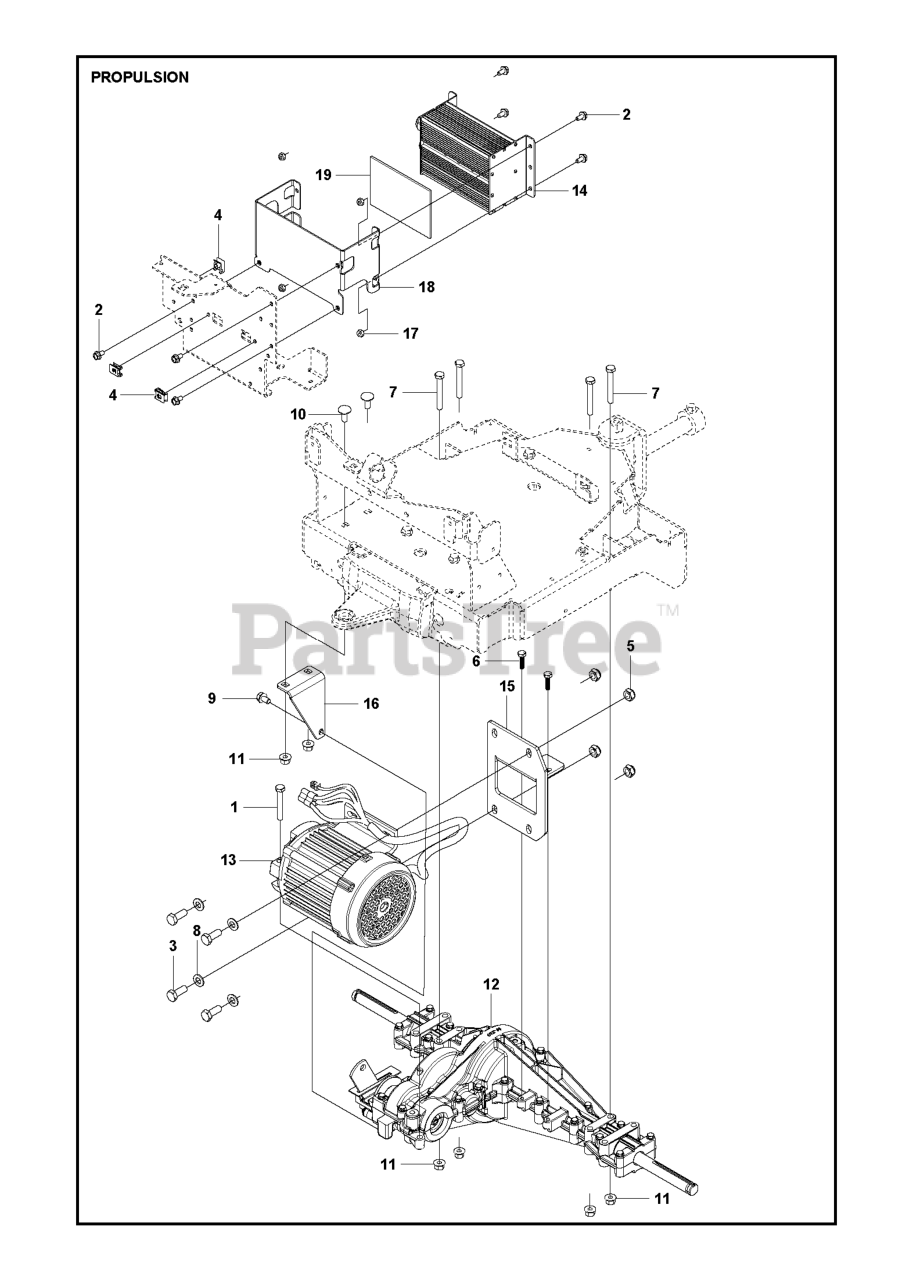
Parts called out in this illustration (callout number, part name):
2	SCREW EHHFM
3	Screw M10x25
6	SCREW HEX WASH THDRL BLK 1_4-
8	WASHER
11	NUT FLANGE
17	LOCKNUT M6
